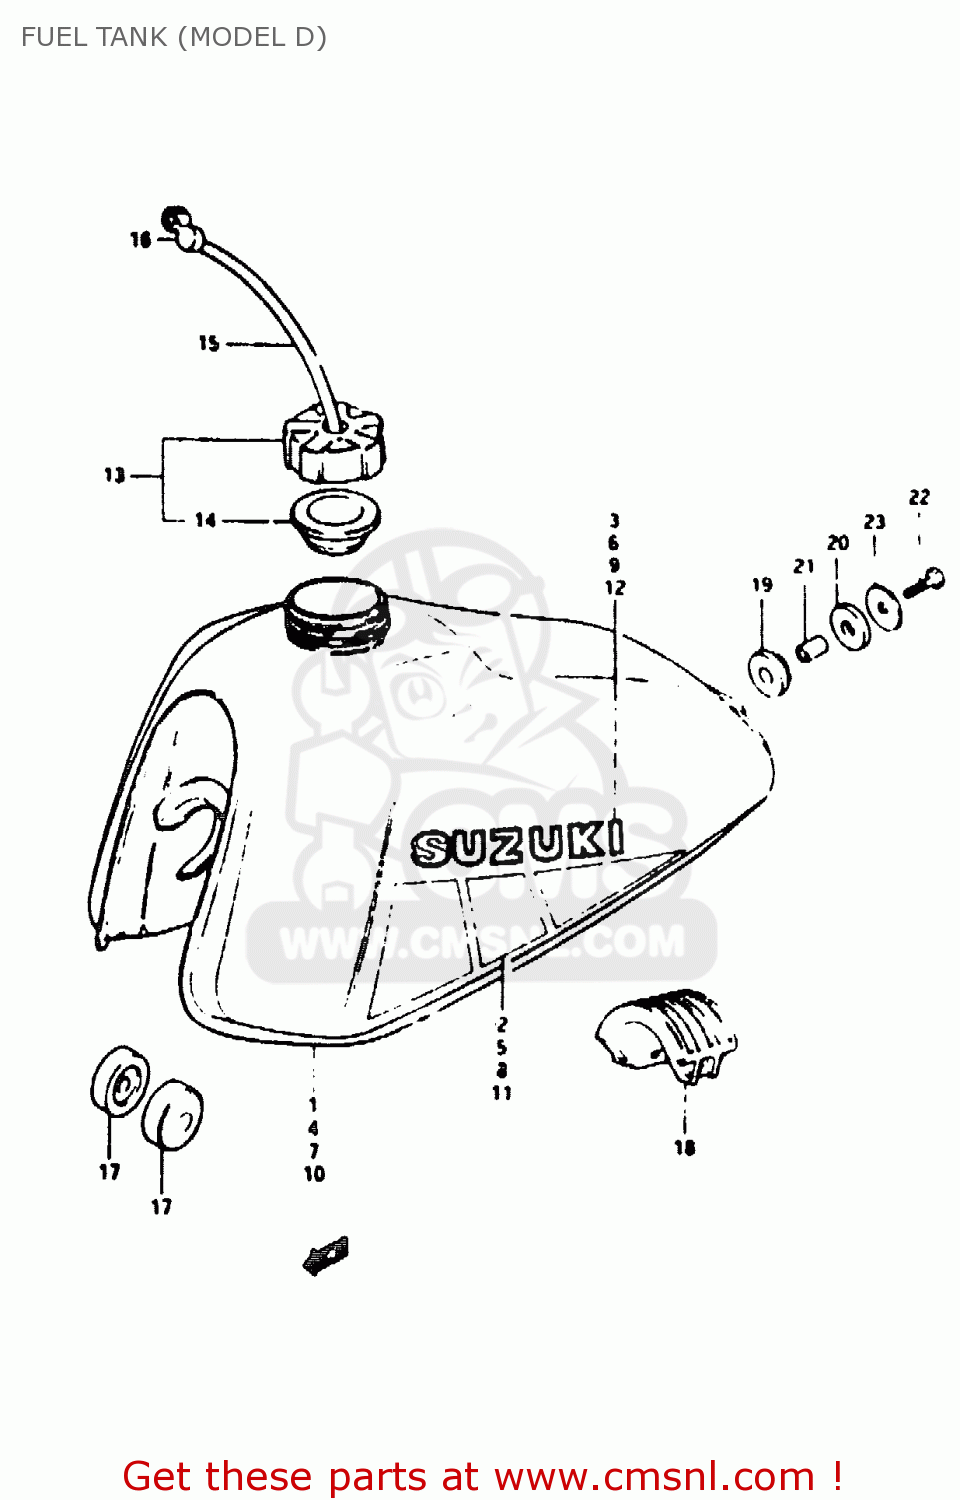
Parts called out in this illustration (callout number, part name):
1	TANK, FUEL (RED)
2	TAPE SET
3	EMBLEM
4	TANK, FUEL (BLACK)
5	TAPE SET, FUEL TANK
6	EMBLEM
7	TANK, FUEL (BLUE)
8	TAPE SET
9	EMBLEM
10	TANK, FUEL (YELLOW)
11	TAPE SET
12	EMBLEM(BLACK)
13	CAP,FUEL TANK
14	GASKET,FUEL TANK CAP (NAS)
15	HOSE
16	CLAMP,FUEL TANK BREATHER HOSE
17	CUSHION
18	CUSHION,FUEL TANK UPR
19	CUSHION
20	CUSHION
21	SPACER(8.5X12X19)
22	BOLT (8X30)
23	WASHER (8.5X29X1.6)
